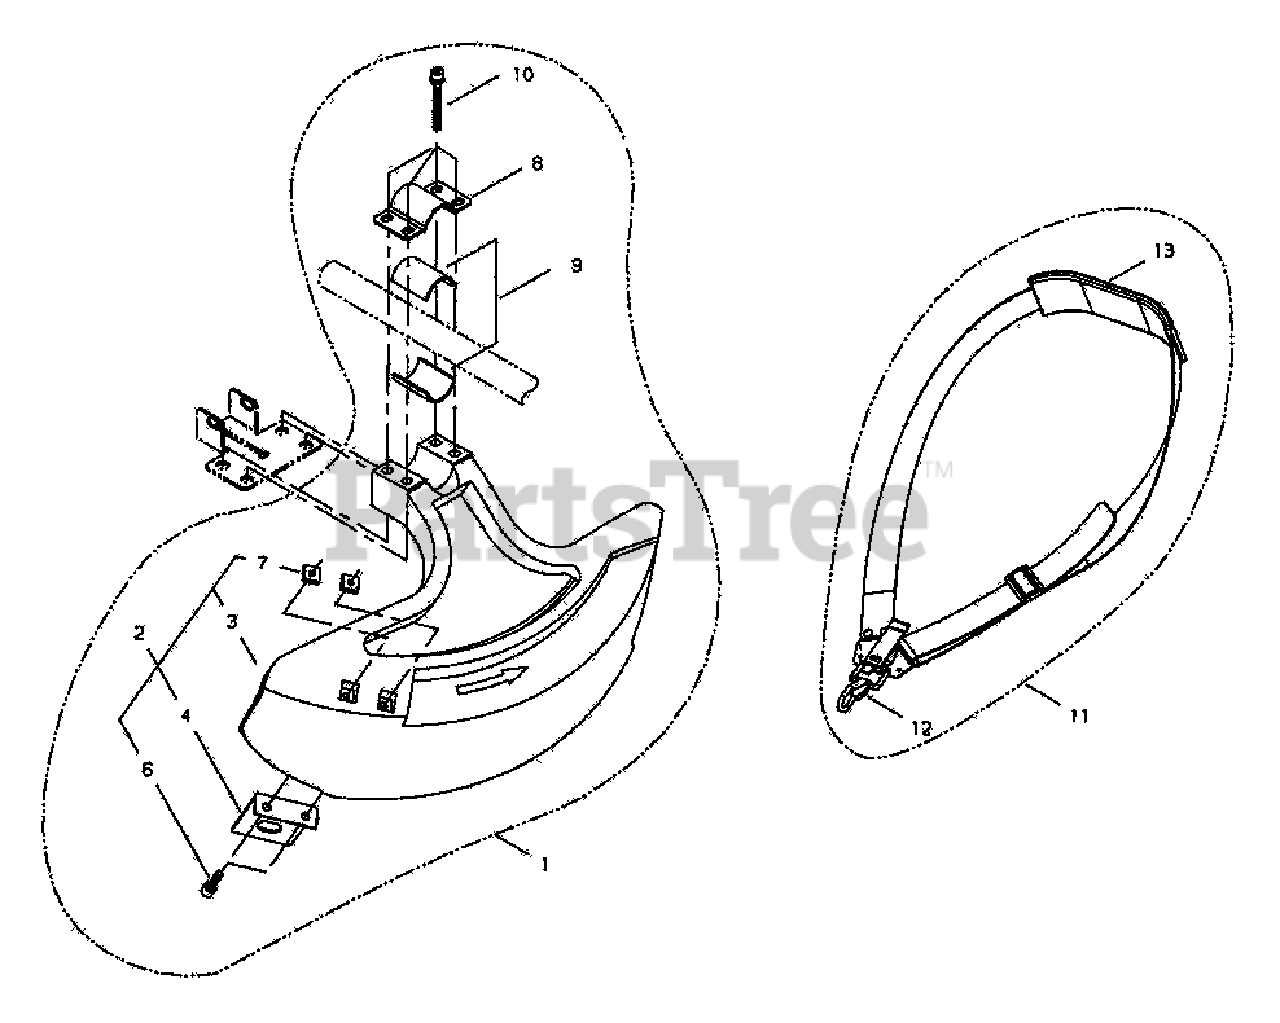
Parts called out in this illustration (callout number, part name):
1	GUARD ASSY
2	SHIELD SUB ASSY
3	SHIELD
4	KNIFE, TRIMMER LINE
6	SCREW - 5X22
7	NUT - 5
8	CLAMP - UPPER
9	SPACER
10	SCREW - 5X45
11	HARNESS ASSY
12	HOOK
13	PAD
